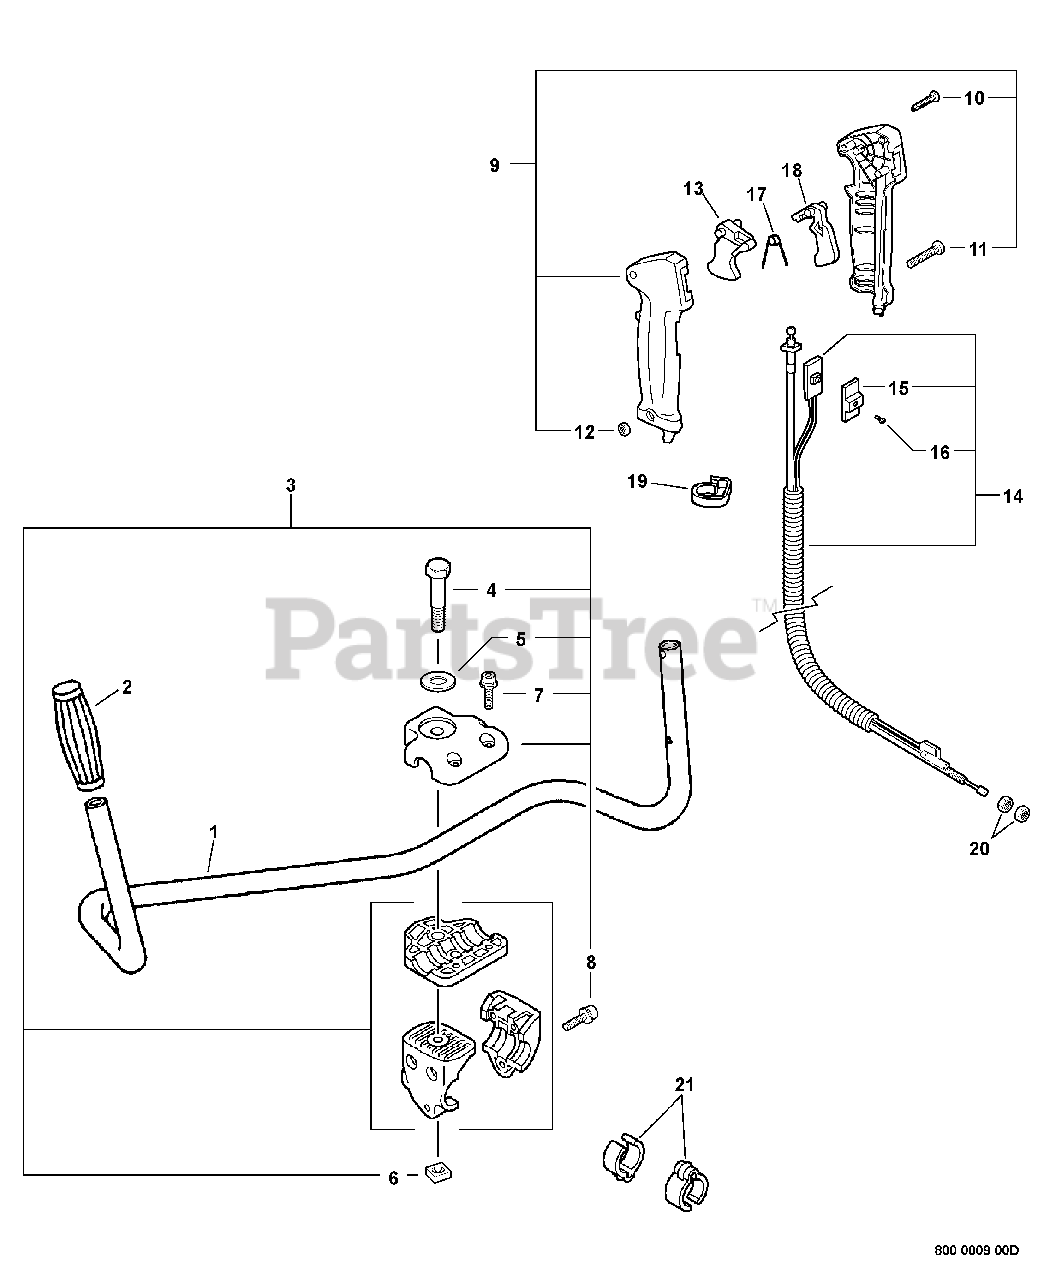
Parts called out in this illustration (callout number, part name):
1	HANDLE - FRONT
2	GRIP, HANDLE - LEFT
3	HANDLE BRACKET KIT
4	BOLT - 8X55
5	WASHER - 8
7	SCREW - 5X20
8	SCREW - 5X30
9	THROTTLE CONTROL ASSY
10	SCREW - 3X25
11	SCREW - 5X30
13	TRIGGER, THROTTLE
14	CONTROL CABLE ASSY
15	KNOB, SWITCH - ORANGE
16	SCREW - 3X10
17	SPRING, LOCKOUT LEVER
18	LOCKOUT, THROTTLE
